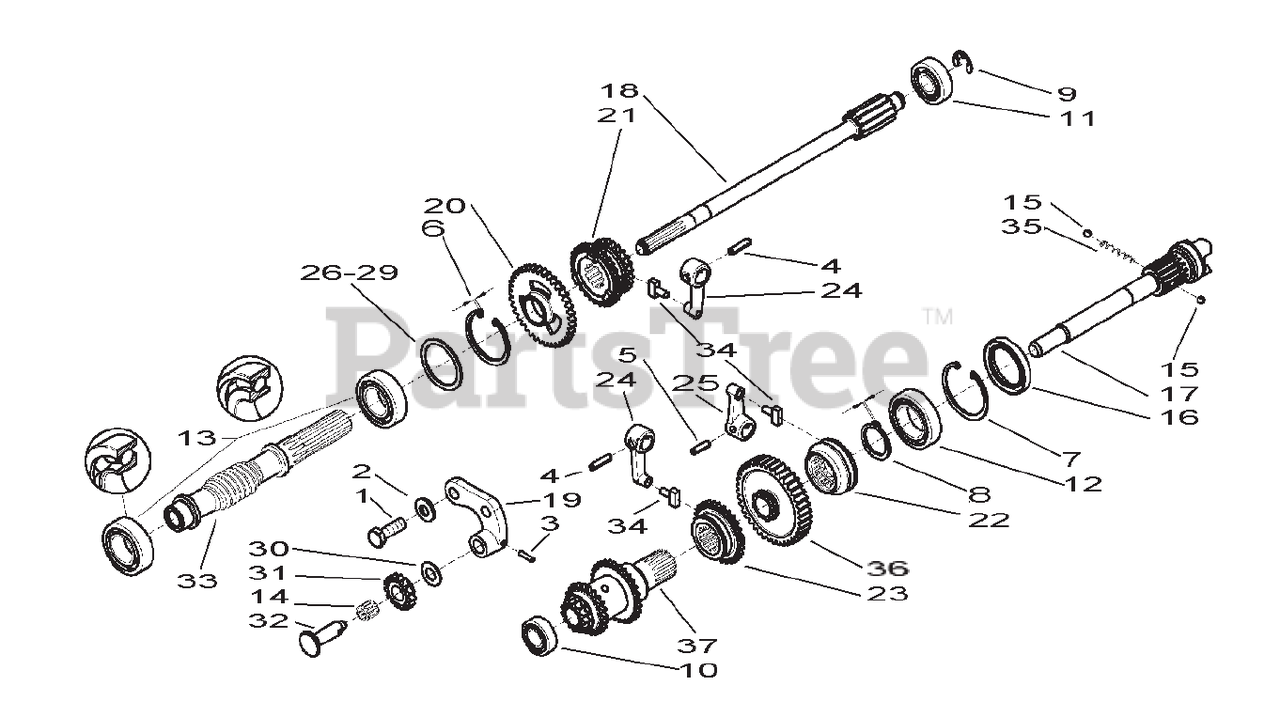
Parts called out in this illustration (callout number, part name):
1	SCREW TE M10X30
2	WASHER
3	ROLL PIN 4X25
4	ROLL PIN
5	ROLL PIN
6	SEEGER RING I 52
7	SEEGER RING I 55
8	SEEGER RING E 30
9	SEEGER RING E 12
10	BEARING
11	BEARING
12	BEARING
13	BEARING
14	ROLLER CAGE 12X15/10
15	BALL 1/4
16	OIL SEAL
17	PTO SHAFT
18	SHAFT
19	GEAR SUPPORT
21	SLIDER
22	COUPLING
23	SLIDER
24	LEVER
25	LEVER
26	SHIM, 1.5MM
27	SHIM, 1.6MM
28	SHIM, 1.7MM
29	SHIM, 1.8MM
32	GEAR PIN
33	WORM SHAFT
35	SPRING
36	PTO GEAR
37	TRIPLE GEAR
